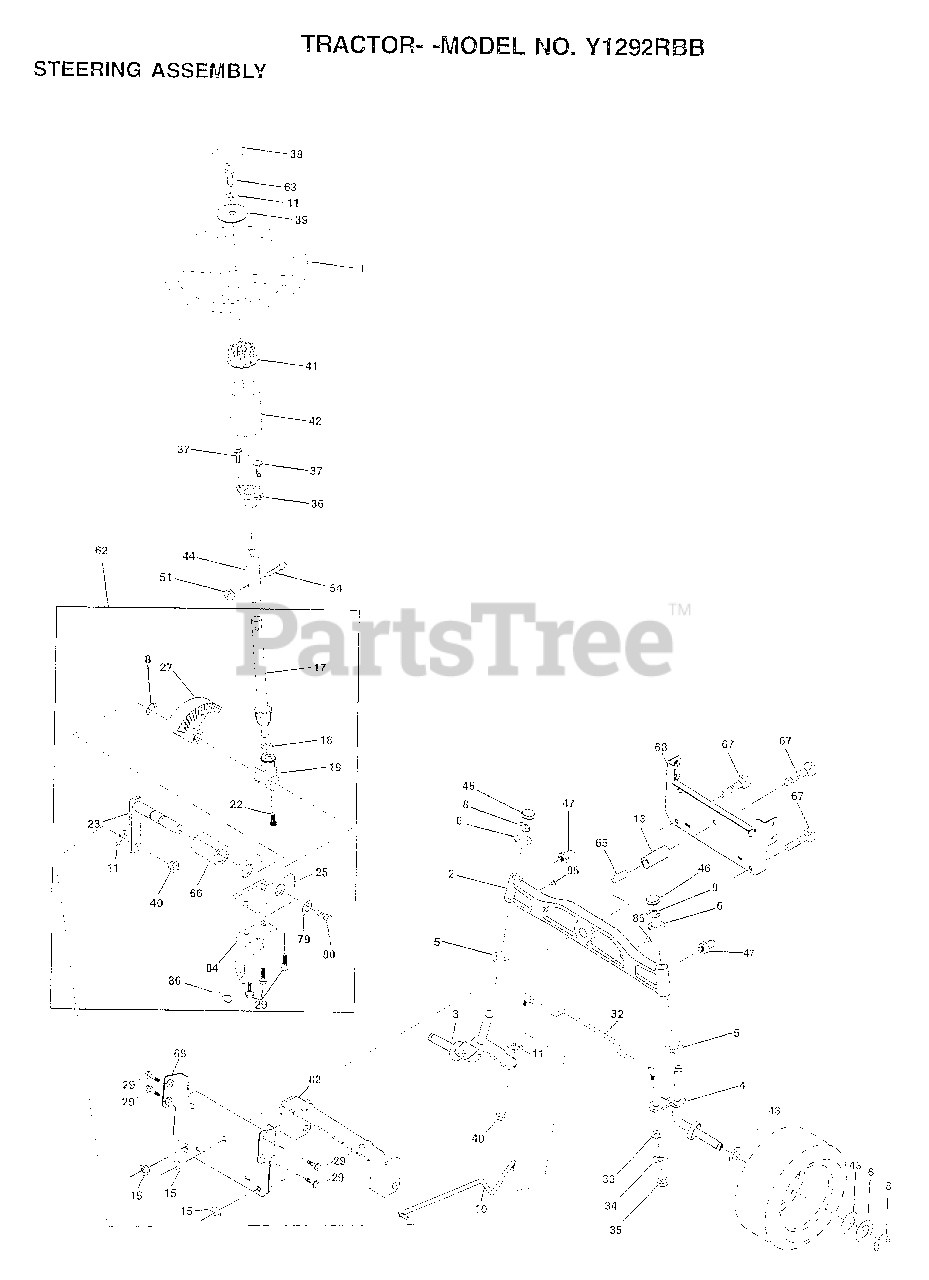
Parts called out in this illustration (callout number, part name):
2	AXLE ASSY
3	SPINDLE ASM
4	SPINDLE ASM
5	WASHER .T
6	WASHER
8	RING
10	LINK DRAG
11	LOCKWASHER
13	SPACER BEARING
15	NUT.HXFLG.LOCK.
17	SHAFT ASM STEERIN
18	THRUST WASHER
19	SUPPORT.SHAFT.STEER
22	SCREW.HX.WSH.HD
23	SHAFT.ASM.PITMAN
25	BRKT-STEERING
27	GEAR SECTOR
29	SCREW
32	TIE ROD
33	WASHER M
34	LOCKWASHER
35	NUT.LOCK.5/16-24
36	BUSHING.STEERING
37	"SCREW-TT,10-32 FL"
38	ST WHL INSERT CAP
39	WASHER
40	GRIPCO NUT
41	ADAPTER LT
42	BOOT.STEERING.DASH.P/L
43	WASHER
44	EXT SHAFT STEERIN
46	CAP
47	ZERK M
51	NUT
54	BOLT
62	KIT.STEER.ASM
63	BOLT
65	"SPACER BRCAE,AXLE"
66	"BEARING-ARM,PITMA"
67	BOLT RDHD 3/8-16
68	BRACE AXLE
79	WASHER
80	BOLT.HX.NYLON3/8-16X3/
82	BRKT SUSP CHASSIS FRT
84	BRACKET CABLE CLUTCH CHASSIS
85	XMAS TREE FASTNER
86	RETAINER SPRING
